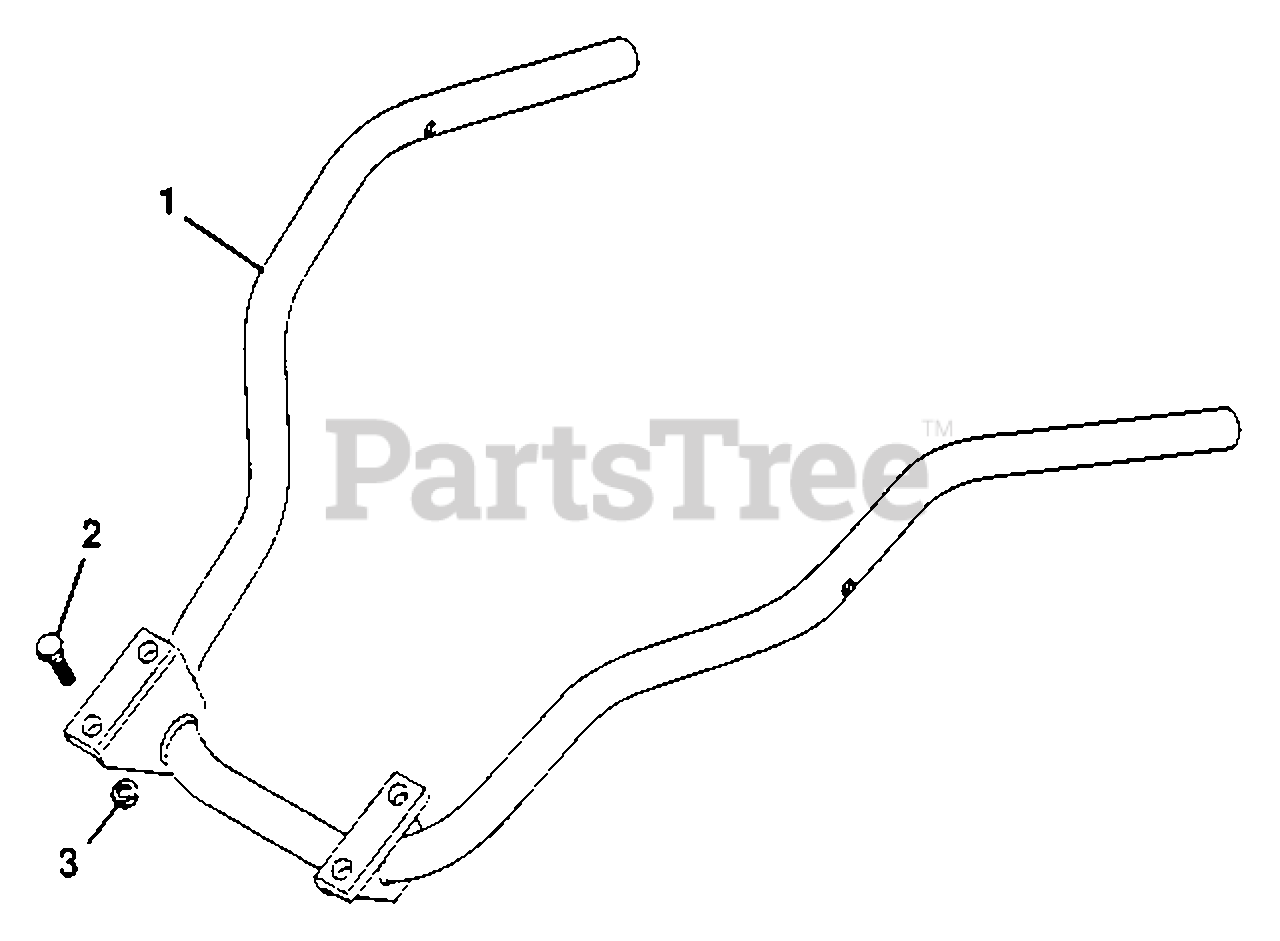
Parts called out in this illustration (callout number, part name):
1	Weldment, Handlebar
2	Bolt, Hex 3/8-16x1.25 Gr. 8
3	Nut, Lock 3/8-16
